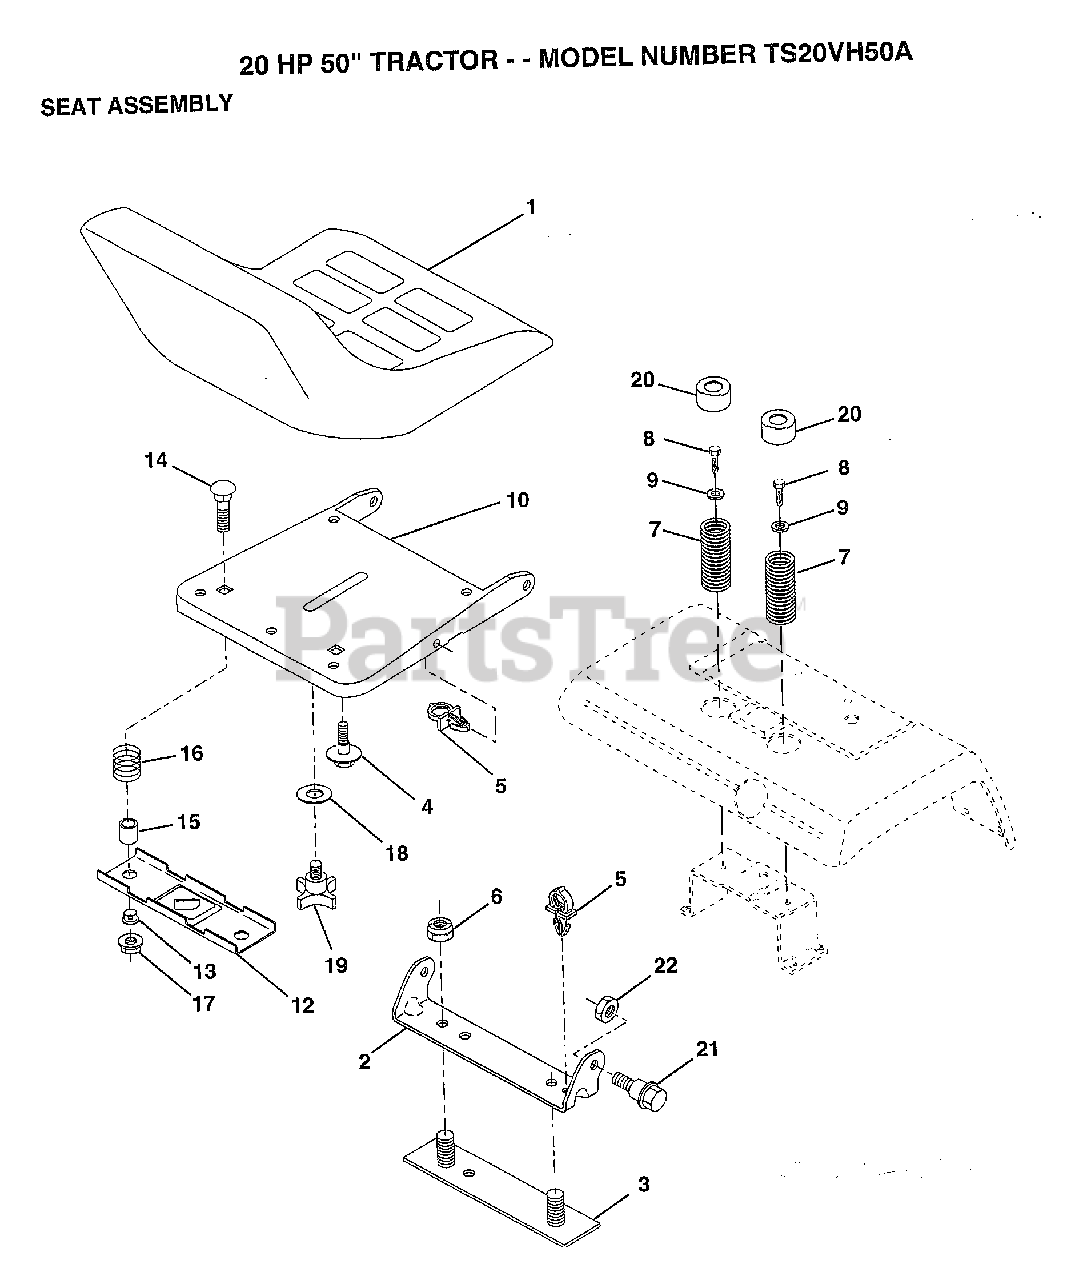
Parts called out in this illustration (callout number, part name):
2	BRACKET PVT SEAT
3	STRAP ASM FENDER
4	"BOLT,SHOULDER"
5	CLIP PUSH - IN
6	NUT
7	SPRING COMPRESSIO
8	SCREW LT
9	WASHER
12	BRKT SWITCH
13	BUSHING
15	SPACER SPLIT
16	SPRING COMPRESSED
18	WASHER
19	"KNOB 1/2"" YT"
20	CAP SPRING
21	BOLT.SHLD.5/16-18
